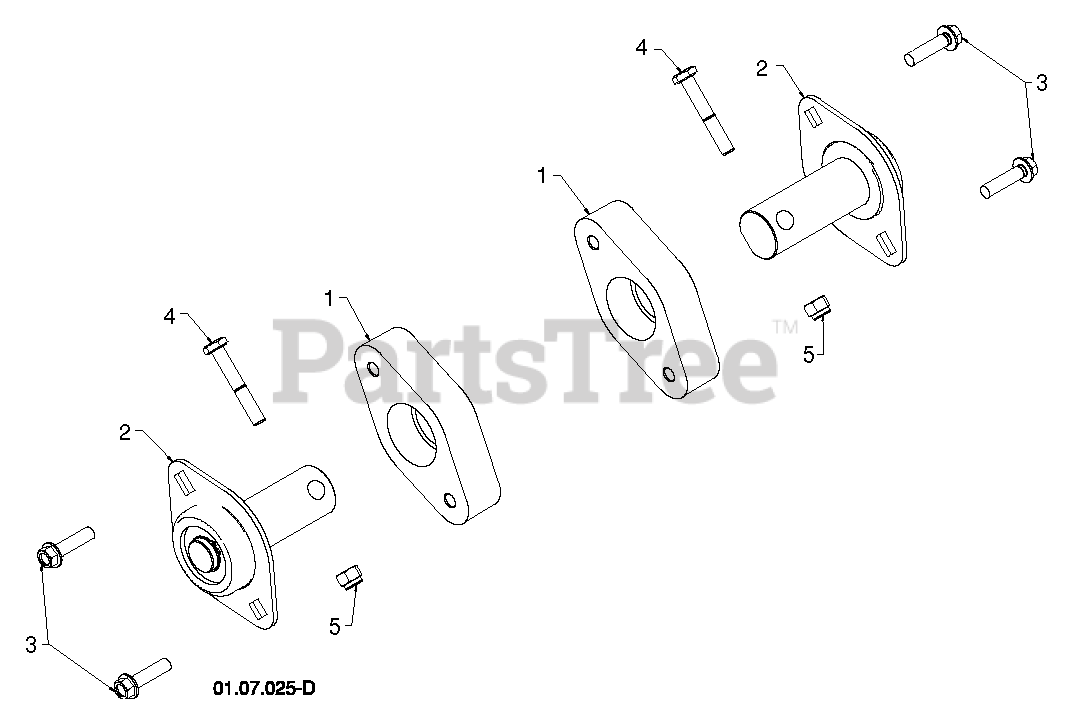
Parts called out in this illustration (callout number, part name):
1	BEARING RETAINER, PLASTIC
2	BEARING.BALL.AUGER.FLAT.
3	SCREW, HEX HD 5/16X1
4	SCREW.HEX.HD1/4-20X
5	LOCKNUT.NYLOC.1/4-20
